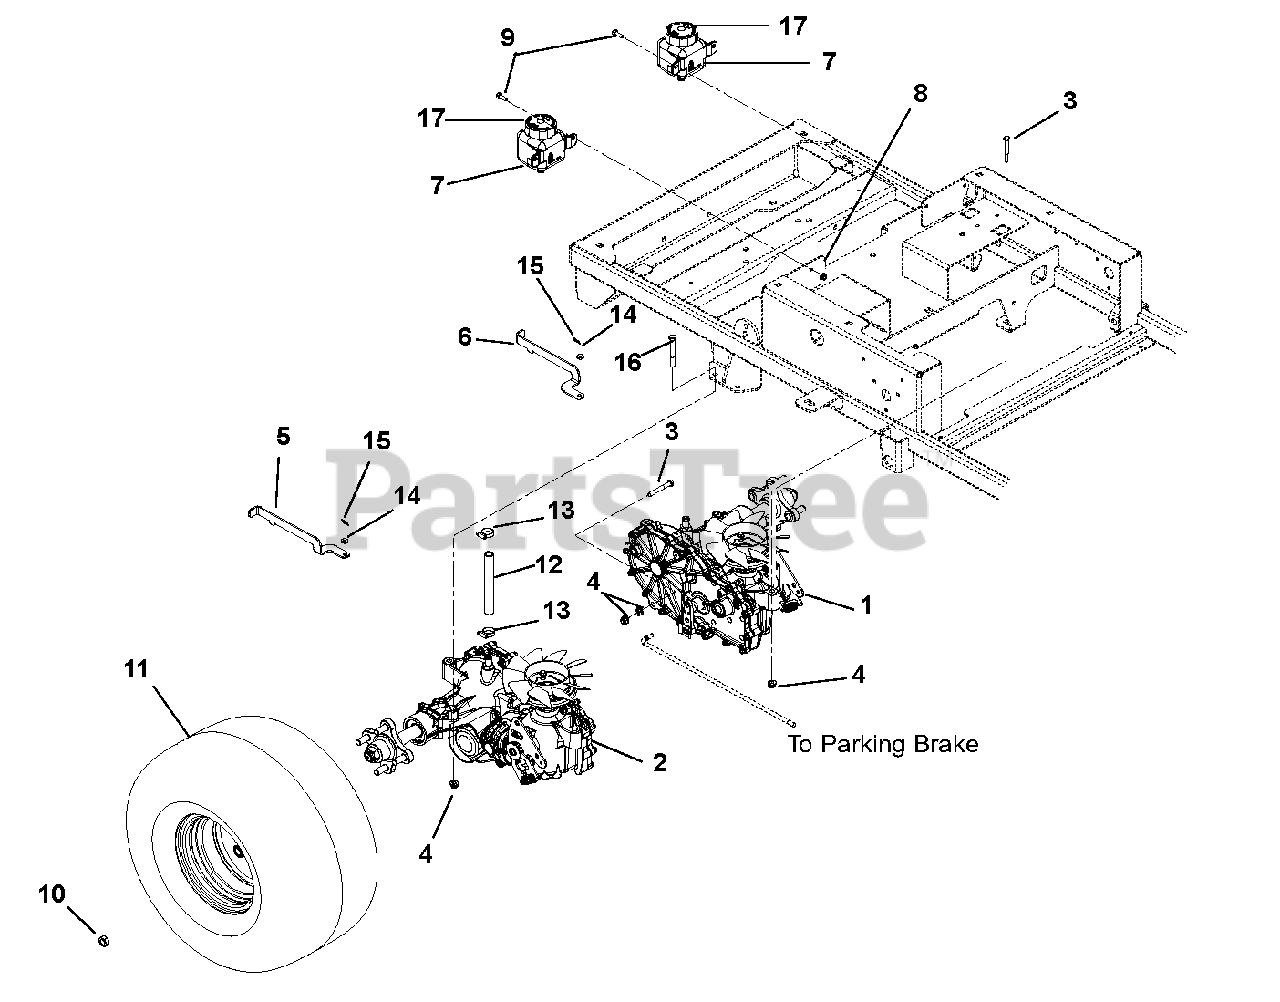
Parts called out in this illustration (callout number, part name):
1	Transaxle, ZT2800 Left Hand
2	Transaxle, ZT2800 Right Hand
3	Bolt, Hex .31-18 x 2.25 Grade 5
4	Nut 5/16-18 Flange Nyloc
5	Dump Valve, Right Hand
6	Dump Valve, Left Hand
7	Tank, Expansion ZT2800
8	Nut, Locking Top Flange .25-20
9	Bolt, Hex .25-20 x .75 Grade 5
10	Nut, Wheel .50-20 13/16
11	Tire/Wheel Assembly, 20 x 10.0-8 Center
12	Hose, Oil Reservior
13	Clamp, .88 Diameter Hose
14	Washer, Flat Steel .265 x .50 x .087
15	Pin, Hair Internal .06 x .18 x .77
16	Bolt, Hex .31-18 x 2.75
17	Cap, Hydro Reservoir Replacement
